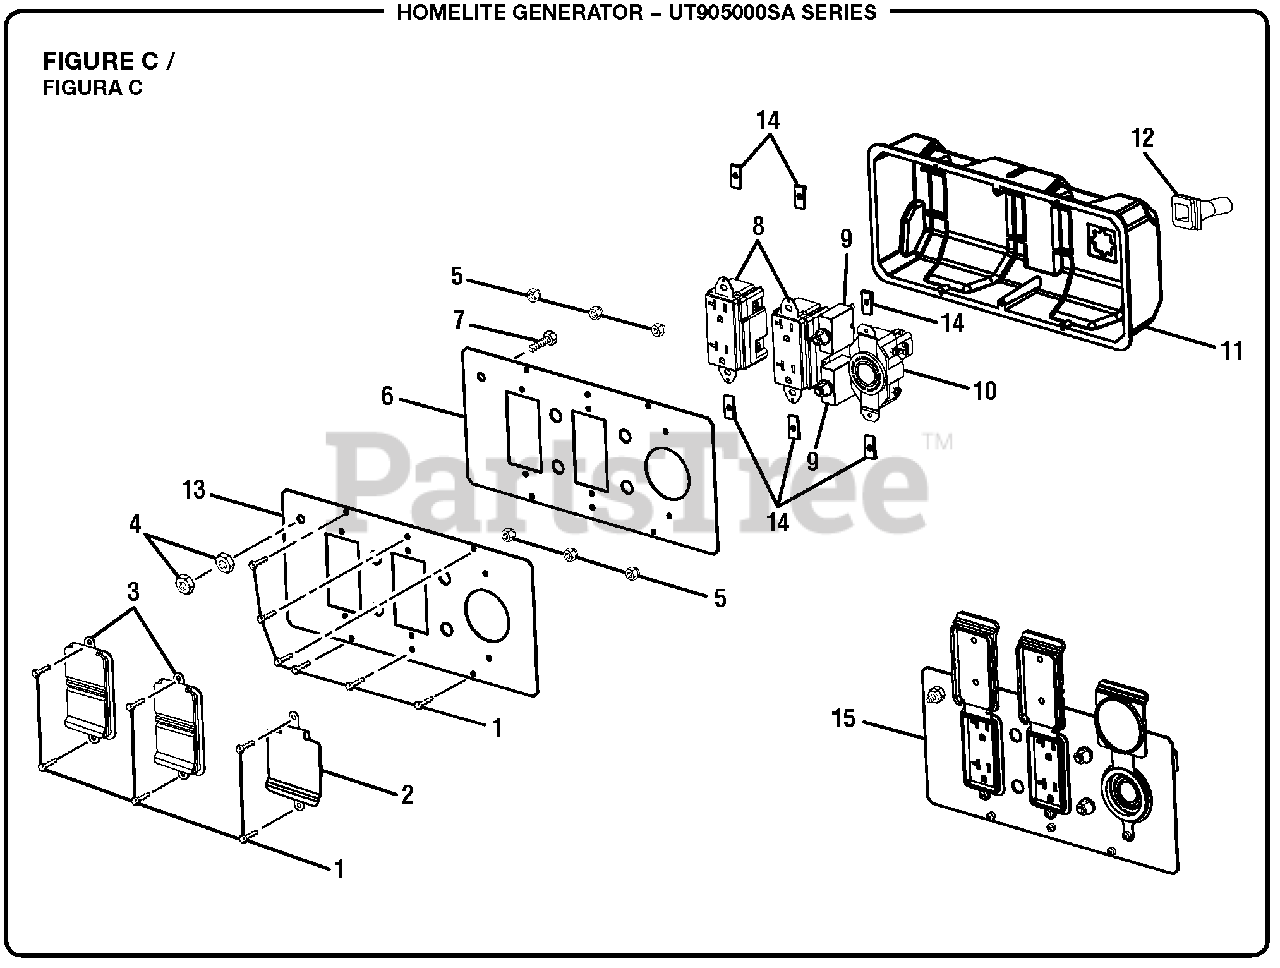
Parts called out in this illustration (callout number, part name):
1	Screw (6-20 x 3/8 in)
2	Outlet Cover (240 V)
3	Outlet Cover (120 V)
4	Hex Nut (1/4-20)
5	Nut (M6-32)
6	Cover Plate
7	Screw (1/4-20 x 5/8 in, Hex Hd)
8	Duplex Receptacle (120 V)
9	Circuit Breaker (20 A, 125 V)
10	Twist Lock Receptacle (120/240 V, 20 A)
11	Rear Control Panel
12	Rubber Boot
13	Control Panel Label
14	Speed Nut
15	Front Panel Assembly
